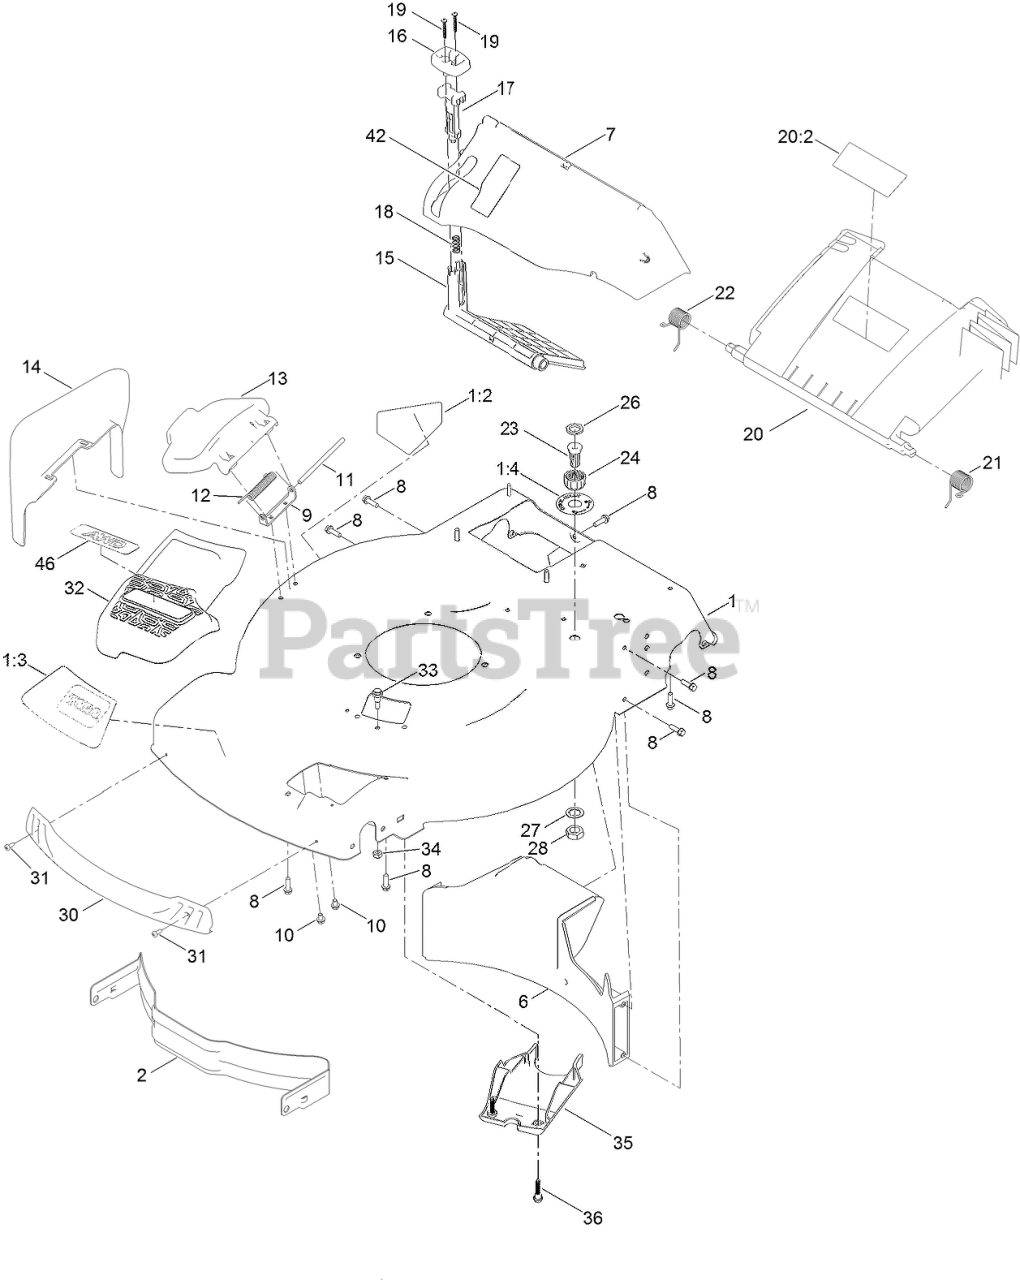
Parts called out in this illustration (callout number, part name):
1	HOUSING ASM
1:2	DECAL-DANGER
1:3	DECAL-DECK
1:4	DECAL-PORT, WASHOUT
2	BAFFLE-FRONT
6	BAFFLE-REAR
7	CHUTE-RECYCLE
8	SCREW-HWH
9	BRACKET-COVER
10	SCREW-HWH
12	SPRING-TORSION
13	DEFLECTOR-SIDE
14	CHUTE-DISCHARGE, SIDE
15	DEFLECTOR-RECYCLE
16	KNOB-RECYCLE
17	LATCH-RECYCLE
18	SPRING-COMPRESSION
19	SCREW-PPH
20:2	DECAL-WARNING
21	SPRING-TORSION
22	SPRING-TORSION
23	PORT-WASHOUT
24	COUPLING-HOSE, WASHOUT PORT
26	WASHER-SEAL, WASHOUT PORT
27	WASHER-LOCK
28	NUT-JAM
30	BUMPER
31	SCREW-FORMING, THREAD
32	COVER-BELT, FRONT
33	BOLT-SHOULDER
34	NUT-LOCK, NI
35	COVER-BELT, FRONT
36	SCREW-SHOULDER, HHF
46	DECAL-BELT COVER, POWEREVERSE
